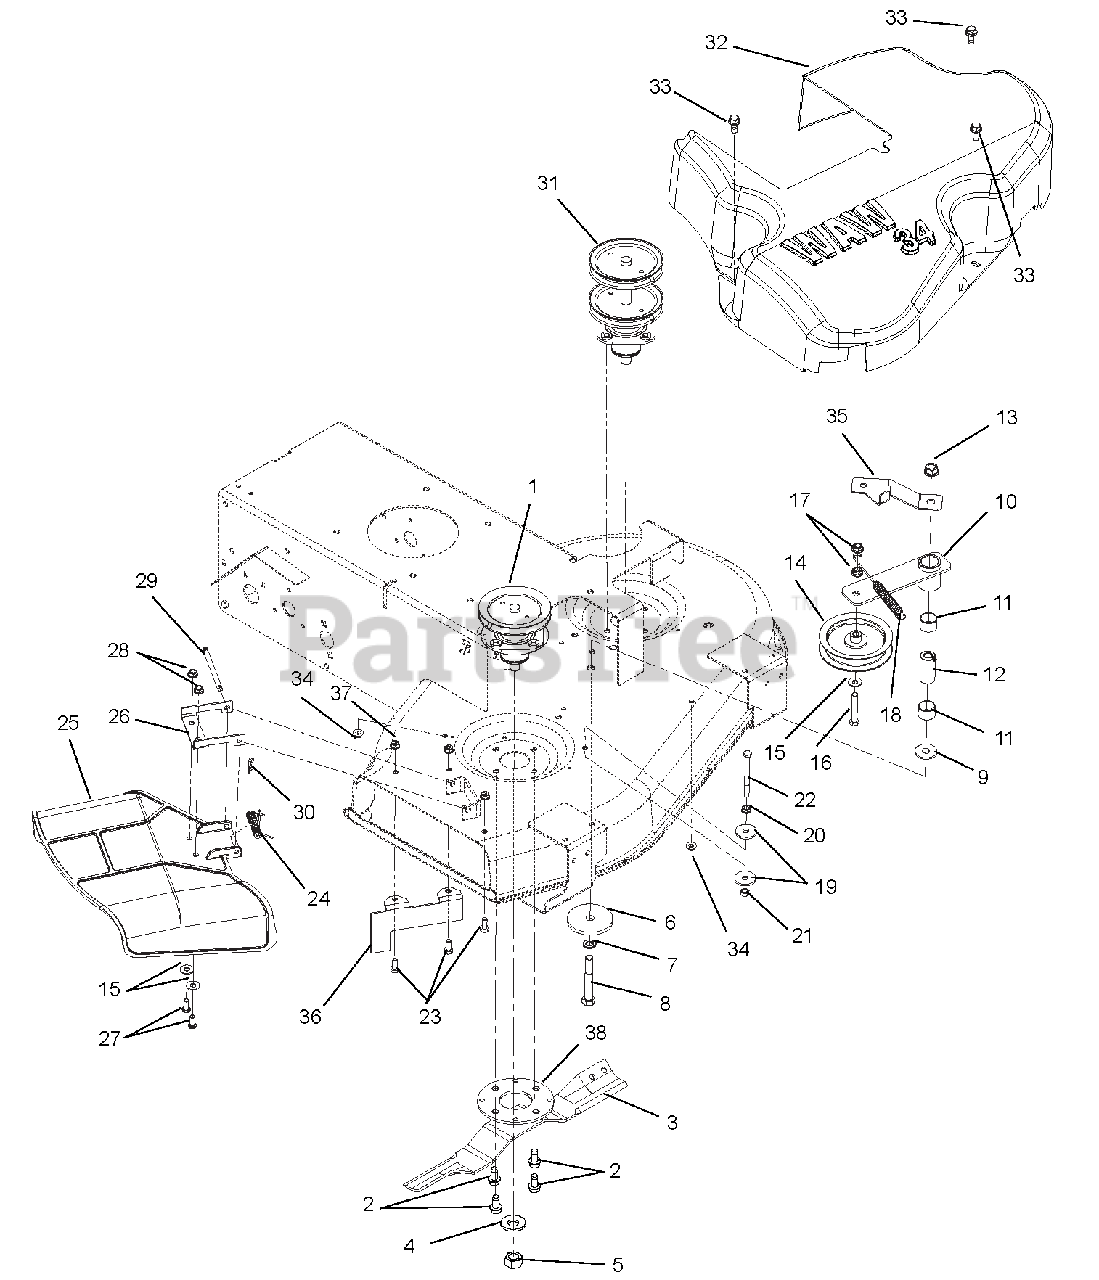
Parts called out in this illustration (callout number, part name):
1	KIT, DECK SPINDLE ASM (34/50)
2	@SCR-TAP .38-16X.75 HWH TR YWZ
3	BLADE-17.2" X .156
4	WSHR-BLVL .669X1.535X.138
5	NUT-HEX .62-18 YWZC
6	WASHER, FLAT .531X3.000X.25
7	@WSHR-LK .50X.125 REG YWZC
8	@BLT-HEX .50-13X3.50 GR5 YWZC
9	WSHR-FL-STL.511X1.441X.125 YWZ
10	ARM, WAW DECK IDLER (WLDMNT)
11	BRG, 1.00 X 1.12 X .75
12	BSHG, SPCR .502X.997X2.03 PM
13	@NUT-LK-TOP-FLG .50-13 YWZC
14	ASM, IDLER 4"
15	@WSHR-FL-STL.38X.875X.083 YWZC
16	@BLT-HEX .38-16X2.25 GR5 YWZC
17	NUT-LK-CTR-FLG .38-16 YWZC
18	SPRING - ENGINE - TRANS.
19	WSHR-FL-STL .406X1.375X.135 YZ
20	@NUT-SPNLK-FLG .312-18 YWZC
21	@NUT-LK-CTR .31-18 YWZC
22	@BLT-HEX .31-18X3.50 GR5 YWZC
23	@BLT-HEX .31-18X.75 GR5 YWZC
24	SPRING, TORSION
25	CHUTE, SIDE DISCHARGE
26	CHUTE REINFORCEMENT
27	SCR-SKH .31-18X.75 BTNHD YWZC
28	@NUT-LK-TOP-FLG .31-18 YWZC
29	PIN, 5/16 X 3.88"
30	PIN-HAIR INT .08X.18X1.18 YWZC
31	KIT, WAW DECK INPUT PULLEY
32	COVER, WAW BELT
33	@SCR-TAP .38-16X.75 HWH TR YWZ
34	RETAINER, .38 PUSH-ON
35	BRKT-IDLER BRACE
36	BRKT-BAFFLE, DISCHARGE 34"
37	@NUT-LK-NYL-FLG .31-18 YWZC
38	PLATE-REINF, SPINDLE
